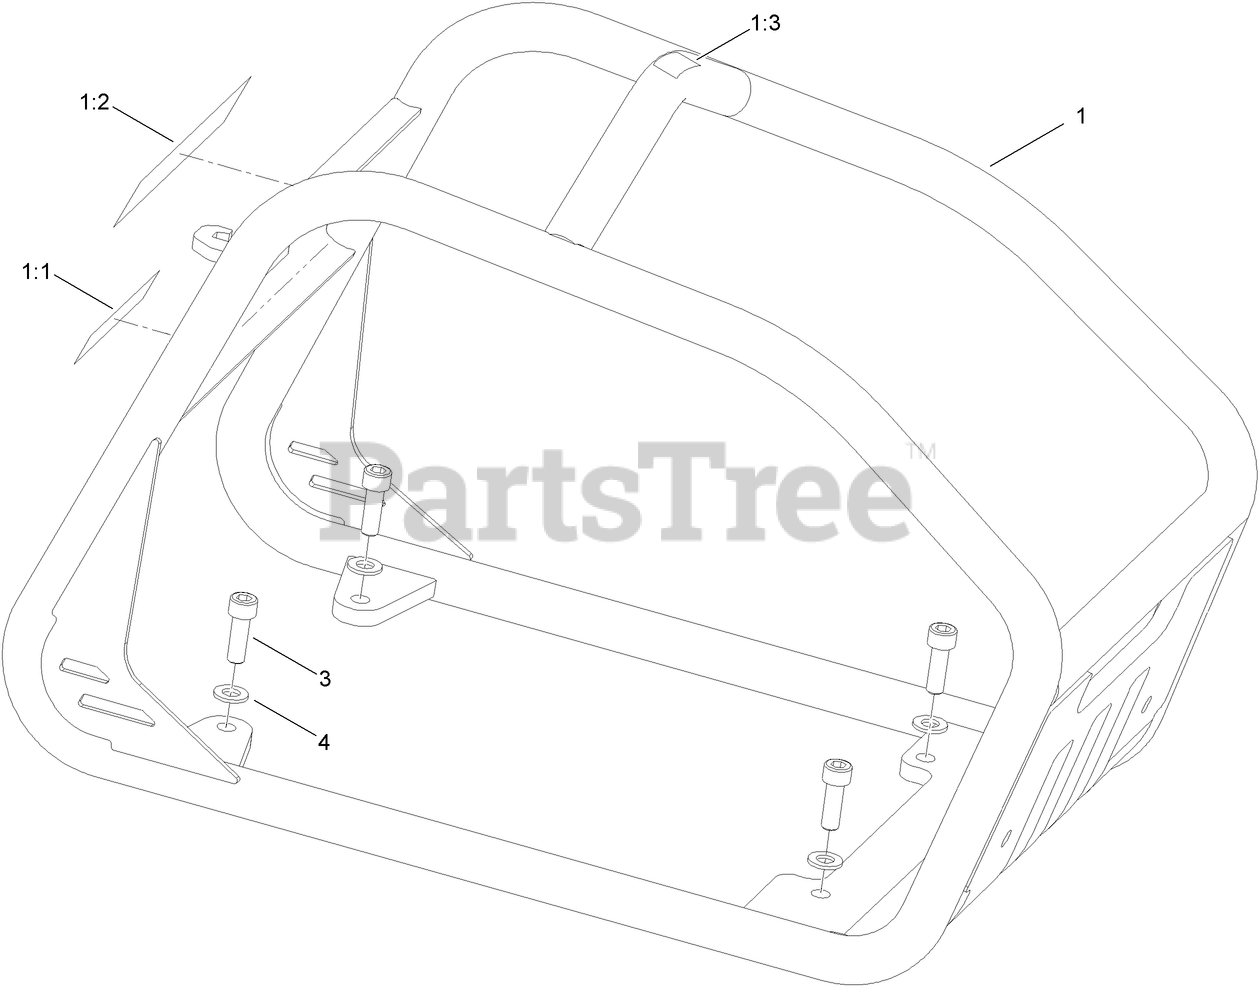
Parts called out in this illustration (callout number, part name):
1	CAGE-ENGINE
1:1	DECAL-ARRESTER, SPARK
1:2	DECAL-WARNING, PLATE
1:3	DECAL-POINT, LIFT
4	WASHER
